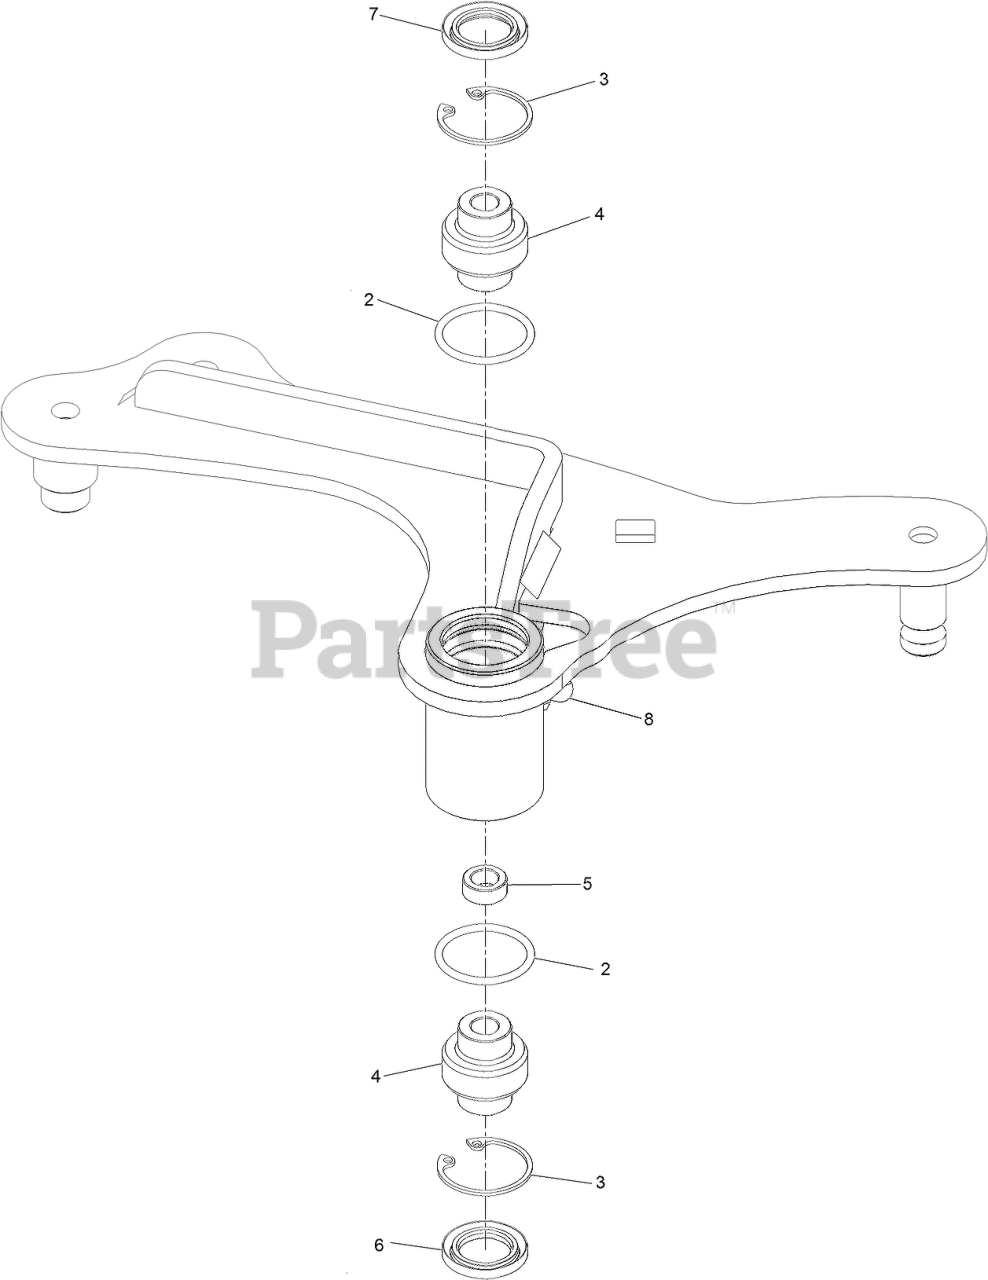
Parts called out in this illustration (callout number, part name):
3	RING-SNAP
4	BEARING-SPHERICAL
6	SEAL-LIP, DOUBLE
7	SEAL-LIP, SINGLE
8	FITTING-GREASE, 90 DEG
